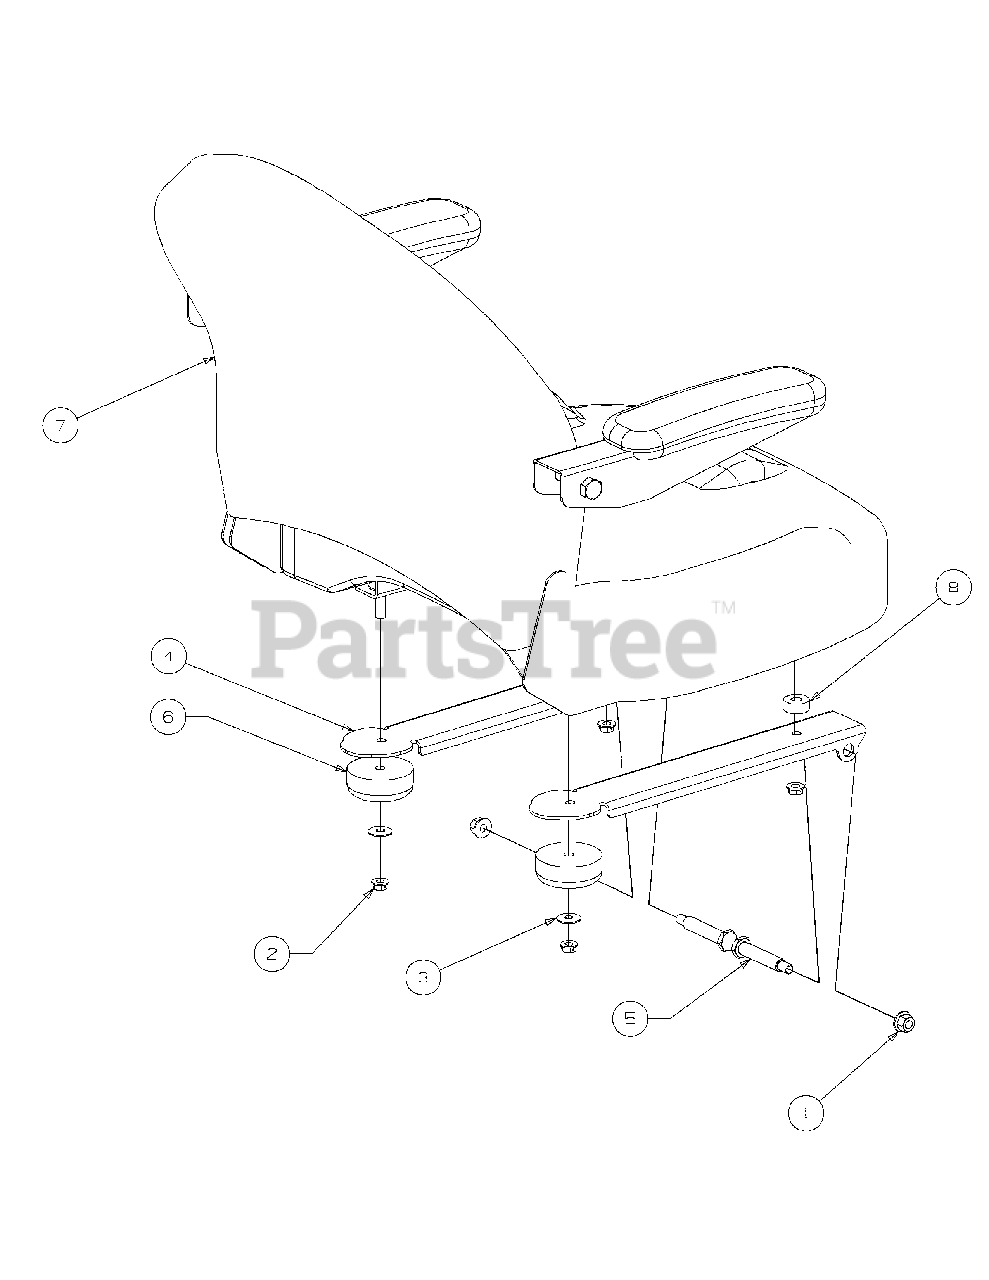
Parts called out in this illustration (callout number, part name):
1	Nut, Hex 3/8-16 Flange Lock
2	Lock Nut, Hex Flange, 5/16-18
3	Washer
4	Mounting Bracket, Seat
5	Shoulder Screw, .50x2.345, 3/8-16
6	Grommet, 2.5 OD x 1.0 Long
7	Adjustable Seat includes:
8	Spacer, 0.406 ID x 1.00 OD x .38
